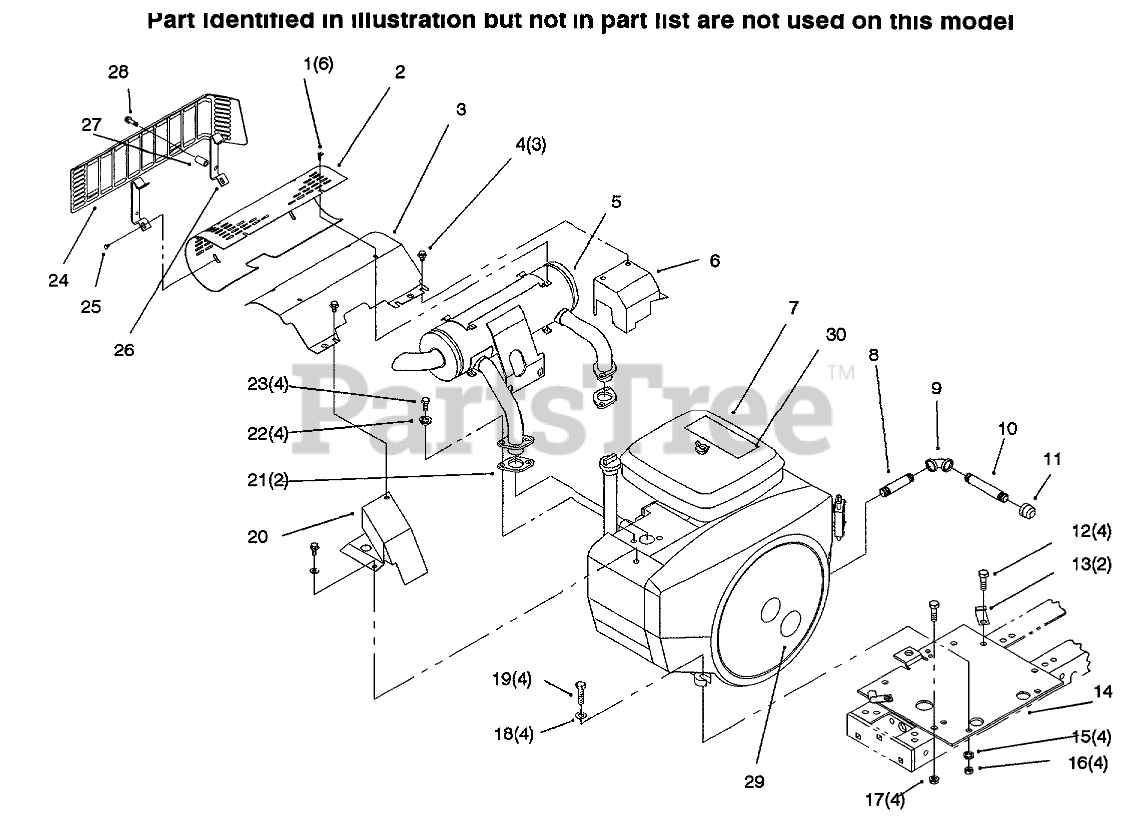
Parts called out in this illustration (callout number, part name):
1	SCW 10-24 STAINLESS
2	SHIELD - HEAT
3	BAFL DEFLCTORB
4	SCREW
5	MUFFLER-EXHAUST
6	RH Exhaust Cover
7	Engine-Onan
8	Pipe
9	ELBOW 3/8 90 DEG
10	PIPE-NIPPLE 3/8 X 4"
11	CAP-PIPE
12	SCREW-HH
13	CLIP
14	PLATE-ENGINE B
15	WASHER-LOCK
16	NUT-HEX
17	NUT-LOCK, NI
18	WASHER-FLAT
19	SCREW-HH
20	LH Exhaust Cover
21	GASKET
22	WASHER-LOCK
23	SCREW-HH
24	SHIELD - HEAT (BLACK)
25	Screw-Phcr
26	Bar-Guard
27	SPACER
28	SCREW-HWH
29	NAME-PLATE TORO LOGO
30	DECAL-PWR PLUS 16 PL
